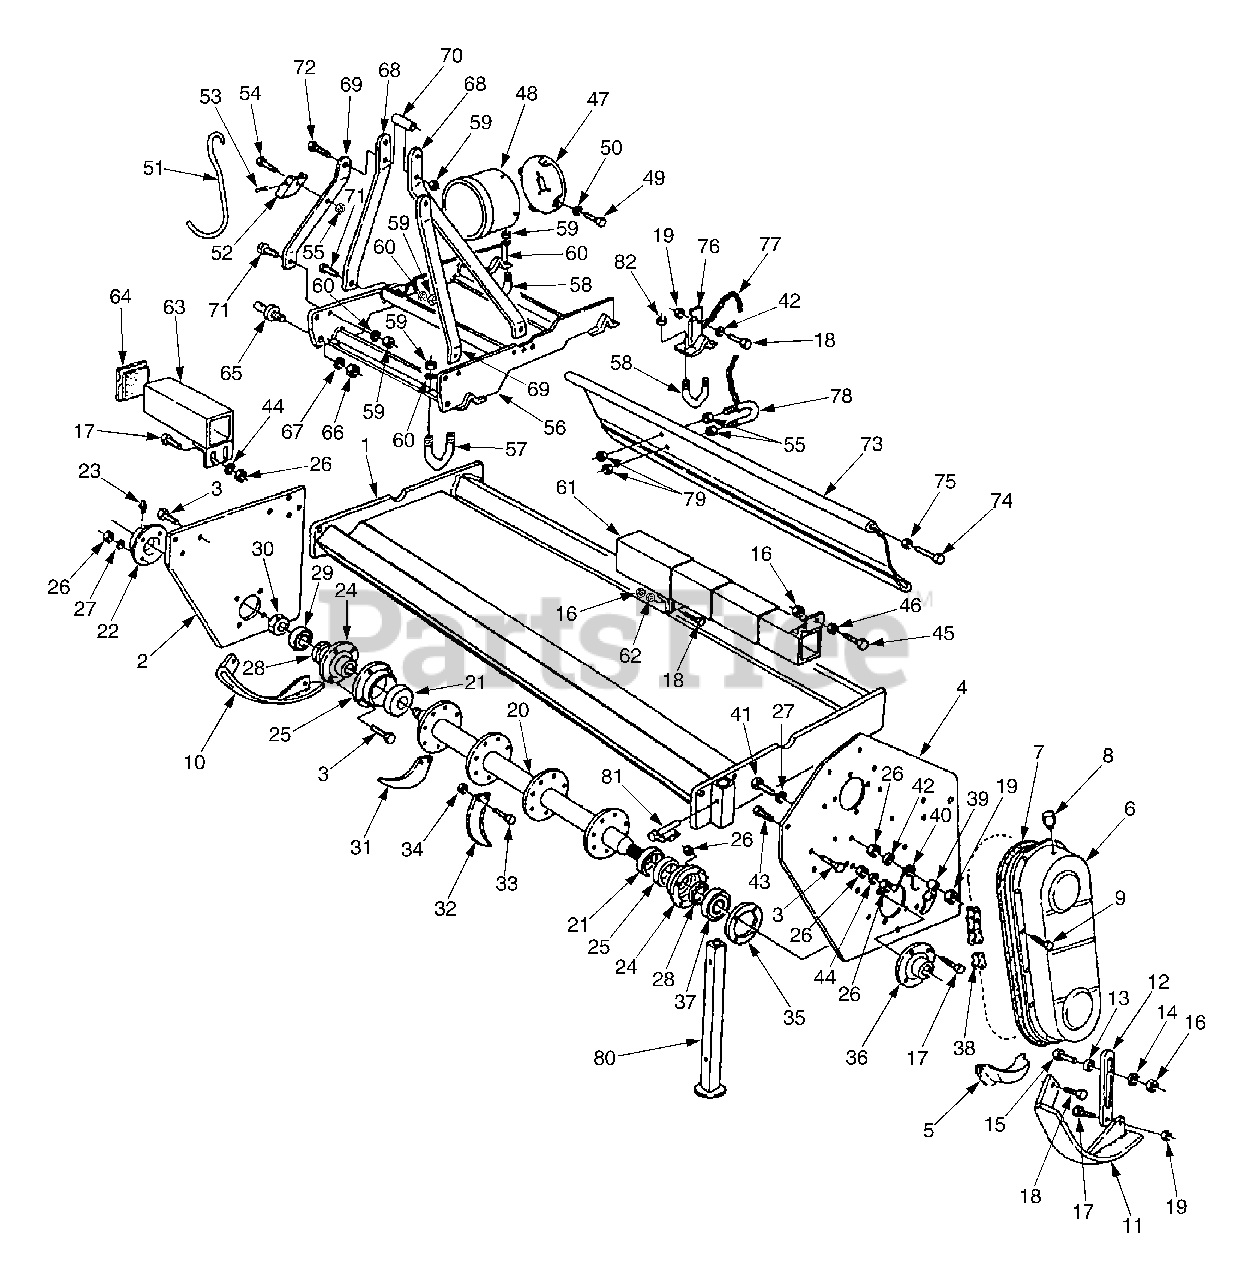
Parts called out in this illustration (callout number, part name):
2	Right Side Panel
4	Drive Panel
5	Chain Case Protection
6	Chain Case Cover
8	Breather Cap
10	Skid - Right
11	Skid - Left
12	Adjustment Arm
13	Threaded Washer
21	Dirt Shield
22	Outer Cover - Right
23	Grease Fitting
30	Safety Nut M30x1.5
31	C-Blade - Right
32	C-Blade - Left
35	Disk (w/Hole)
36	Outer Cover Left
38	Chain ASA 80x36
39	Chain Tensioner
42	Flat Washer M10
44	Flat Washer M10
47	Protection Support
48	PTO Shaft Protection
50	Flat Washer M6
51	Driveline Hook
52	Hook Support
53	Cotter Pin D.2
56	Side Shift 3rd Point Hitch
59	Nut M12
61	Protection 58"
63	Right Protection 50"
64	Plastic Cap
68	Top Hitch Arm
69	Top Hitch Support
72	Bolt 12x100
73	Tail Gate 58"
76	Chain Hitch
81	Cotter Pin 10x70
